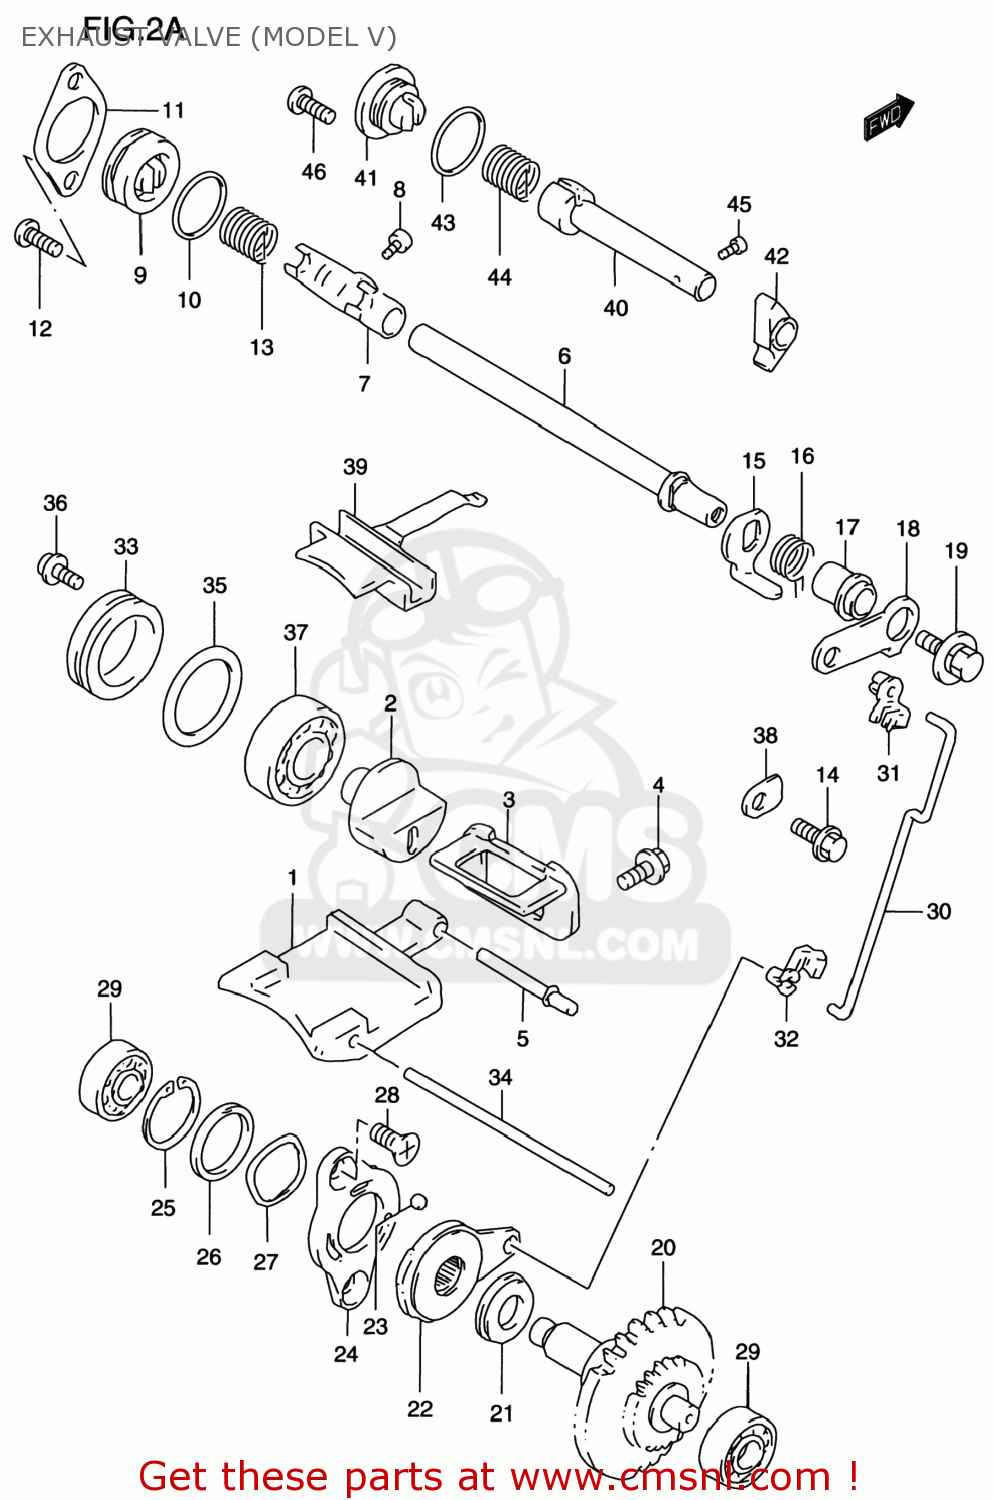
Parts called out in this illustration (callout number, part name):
1	VALVE,EXHAUST MAIN LOW
2	VALVE,EXHAUST SIDE
3	GUIDE,EXHAUST MAIN VALVE
4	SCREW 5X12
5	PIN,EXH MAIN VALVE & SPACER
6	SHAFT,EXHAUST VALVE
7	ARM,EXHAUST VALVE SHAFT
8	BOLT(4X8)
9	CAP,EXHAUST VALVE
10	O RING(D:1.9,ID:22.6)
11	RETAINER,EXHAUST VALVE
12	BOLT
13	SPRING
14	BOLT
15	LEVER,EXHAUST VALVE NO.2
16	SPRING
17	SPACER,EXHAUST VALVE
18	LEVER,EXHAUST VALVE NO.1
19	BOLT(5X12)
20	GOVERNOR ASSY,EXHAUST VALVE
21	BEARING(10X22X2.8)
22	ACTUATOR,EXHAUST VALVE
23	BALL
24	STARTER,EXHAUST VALVE ACTUATOR
25	CIRCLIP
26	SHIM(19.1X25X0.3)
27	WASHER
28	SCREW(5X10)
29	BEARING(8X22X7)
30	ROD,EXHAUST VALVE
31	BUSH,EXHAUST VALVE ROD NO.1
32	BUSH,EXHAUST VALVE ROD NO.2
33	CAP,EXHAUST SIDE VALVE
34	PIN
35	O RING(D:3.1,ID:26.4)
36	SCREW 5X12
37	BEARING
38	RETAINER
39	VALVE,EXHAUST MAIN,MIDDLE
40	SHAFT,CYLINDER COVER,N
41	CAP,CYLINDER COVER NO
42	ARM,CYLINDER COVER NO
43	O RING(D:1.9,ID:14.5)
44	SPRING,CYL COVER NO.2 SHAFT
45	BOLT(4X8)
46	SCREW 5X12
